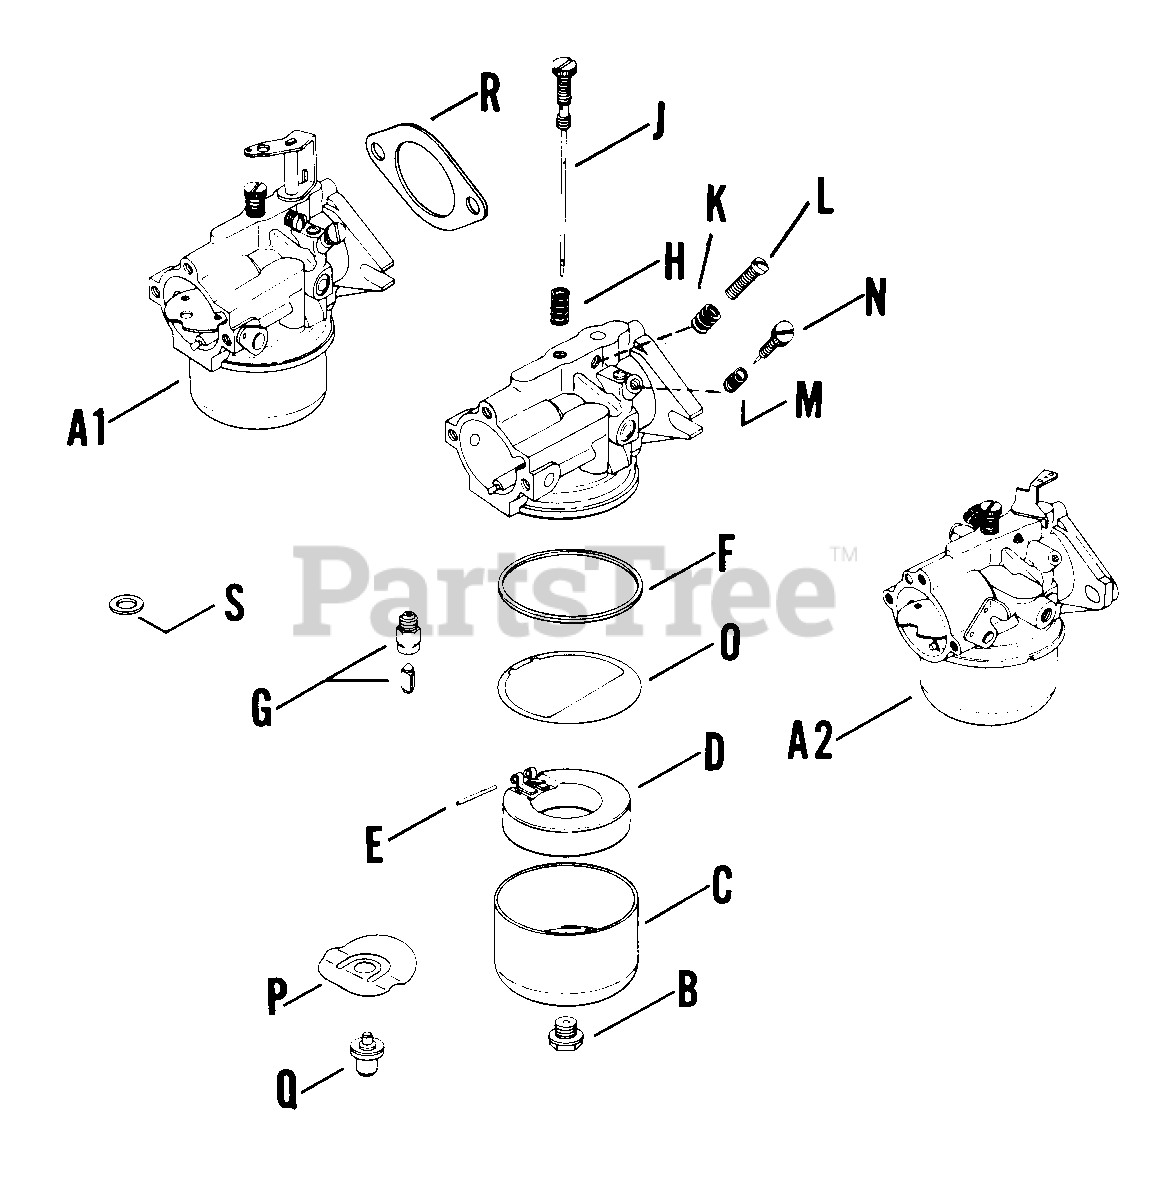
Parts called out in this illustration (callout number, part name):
A1	CARBURETOR - USE 46 853 01
B	NUT - USE 41 100 01
D	KIT - USE 25 757 03
G	NEEDLE - USE 231555
J	NEEDLE - Discontinued
L	SCREW, SPECIAL
M	SPRING - DISCONTINUED
N	SCREW - DISCONTINUED
O	GASKET - USE 25 041 01
S	KIT - USE 25 757 01
